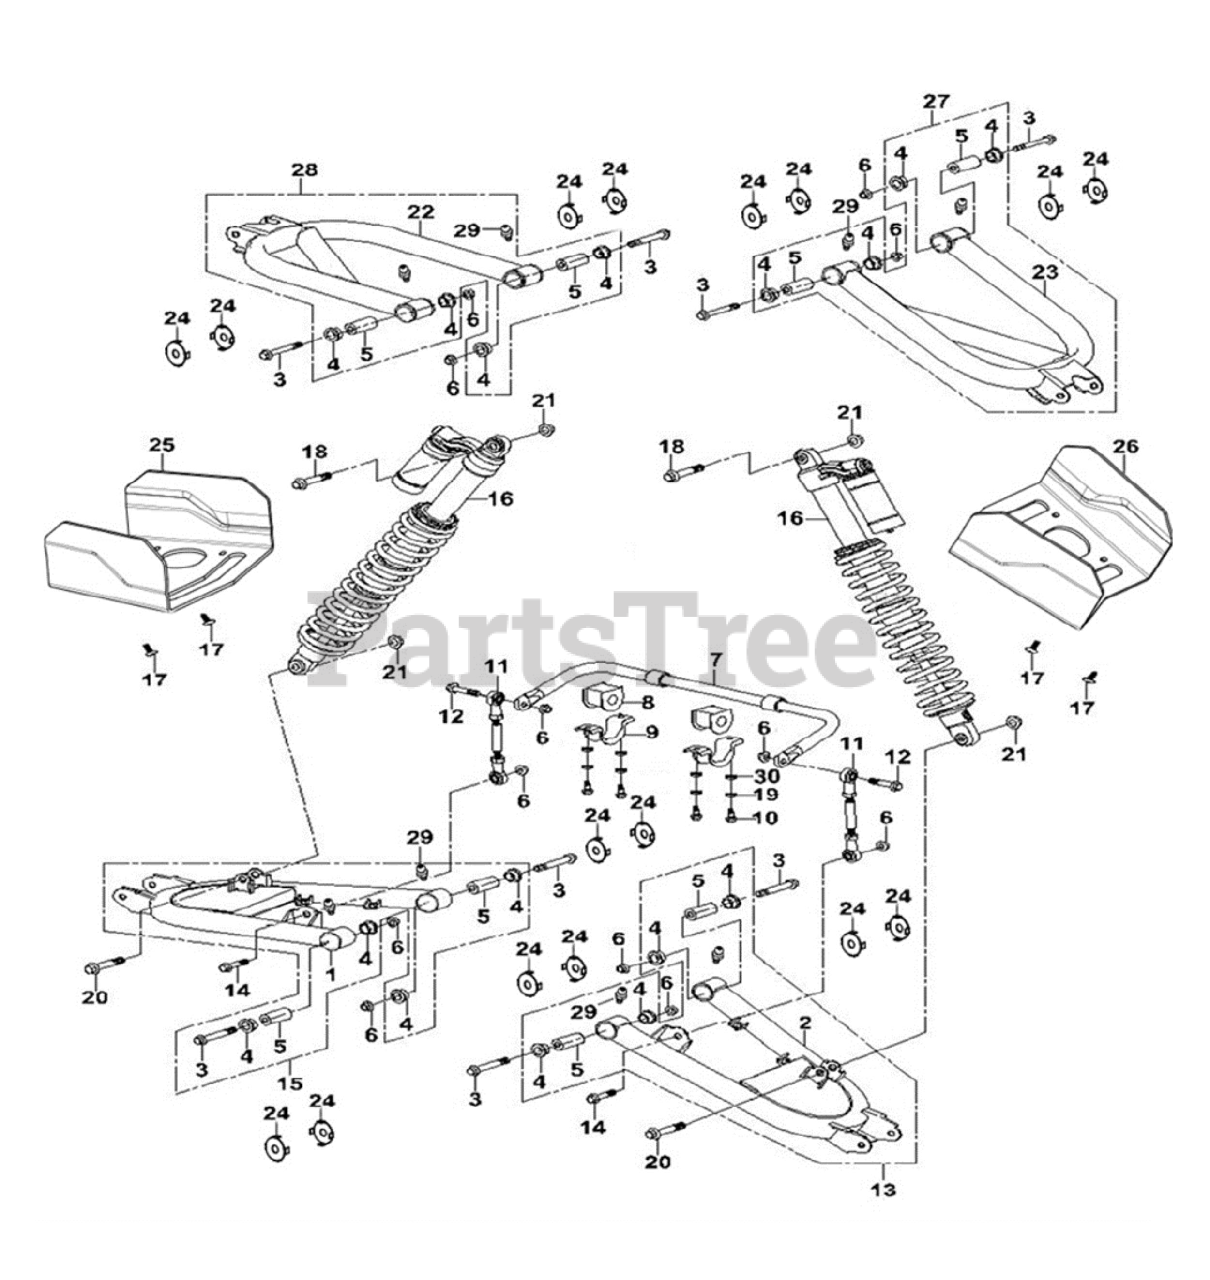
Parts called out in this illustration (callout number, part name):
1	Arm welding kit(rear right lower)
2	Arm welding kit(rear left lower)
3	BOLT HExAGON FLANGE HEAD M10x1.25-80
4	Bush 22x28
5	Bush 10.3x 23x49.4
6	LOCK NUT M10x1.25
7	STABILIZER BAR KIT - REAR
8	Cushion Bush 20x45,balancing lever
9	mounting cap,cushion rubber
10	Hexagon Flange Bolt M8x20
11	ROD BALL KIT - REAR
12	Hexagon Flange BoltM10x1.25x50
13	ARM ASSEMBLY - REAR LEFT LOWER
14	Hexagon Flange BoltM10x1.25x45
15	ARM ASSEMBLY - REAR RIGHT LOWER
16	REAR SHOCK ABSORBER Q
17	Cross Large Plate Head Screw M6x16
18	BOLT HExAGON FLANGE HEAD M10x1.25-70
19	Spring Washer-8
20	BOLT HExAGON FLANGE HEAD M10x1.25-65
21	LOCK NUT M12x1.25
22	Arm welding kit(rear right upper)
23	Arm welding kit(rear left upper)
24	BUSHING CAP ?
25	BUSHING CAP - R
26	BUSHING CAP - L
27	ARM ASSEMBLY - REAR RIGHT LOWER
28	ARM ASSEMBLY - REAR RIGHT UPPER
